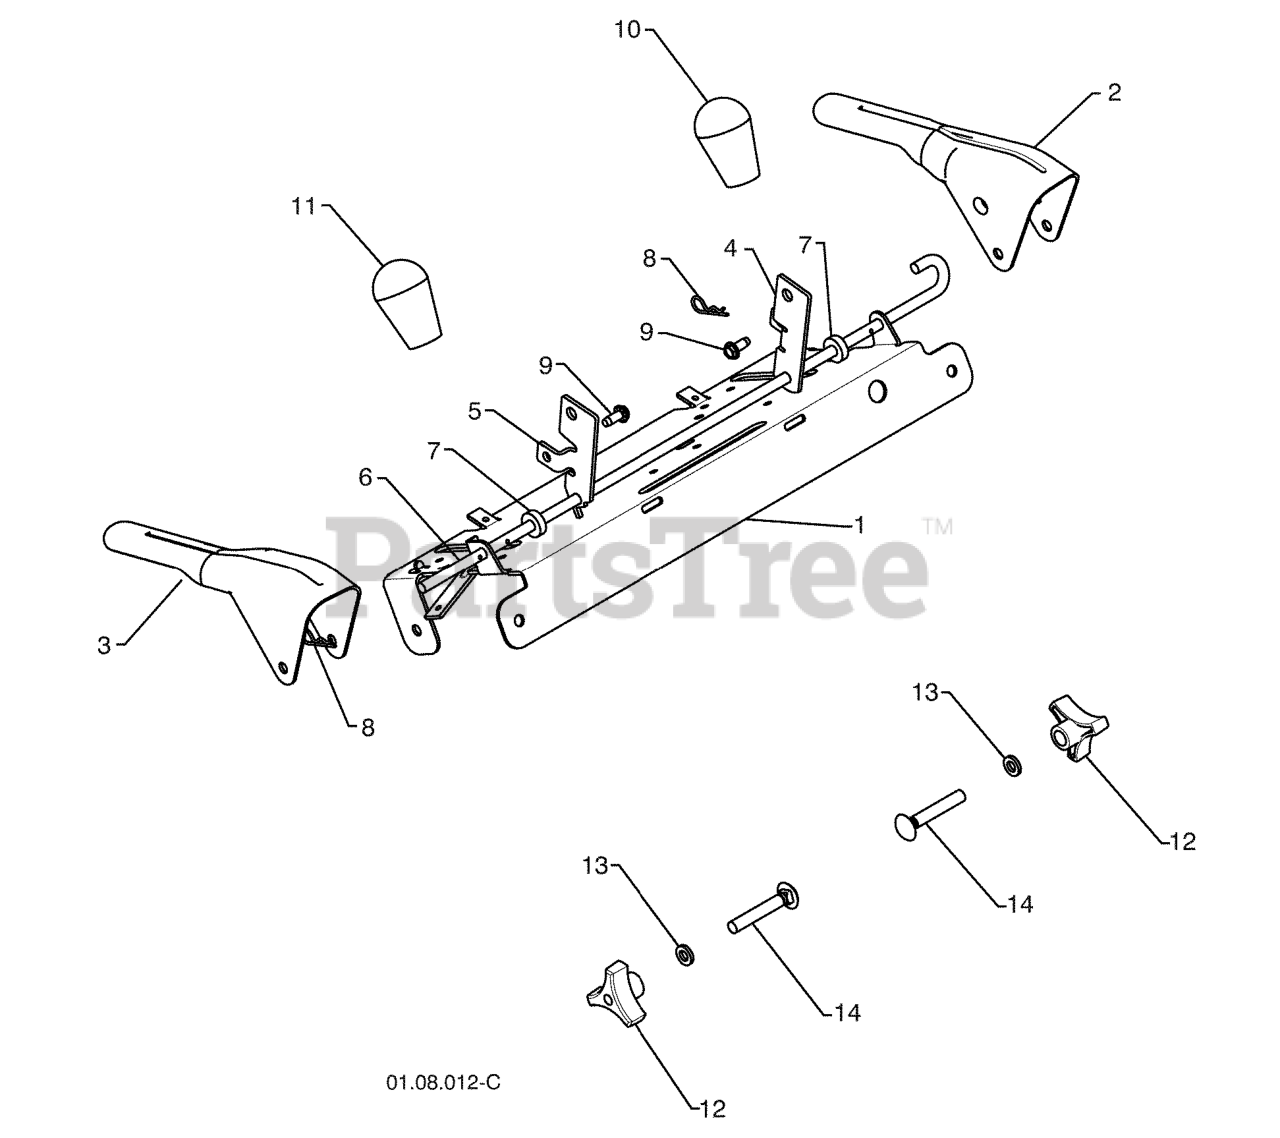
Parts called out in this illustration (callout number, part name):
1	PANEL.CONTROL.PNT.BLACK
2	LEVER.CONTROL.LH.BLACK
3	LEVER.CONTROL.RH.GREY
4	ARM.TRACTION.ROD.YZ
5	ARM.IMPELLER.ROD.SNOW
6	BAIL.CONTROL.INTERLOCK
7	SPACER.CONTROL.LEVER
8	SPRING RETAINER
9	SCREW 14-20 X 5/8
10	KNOB LEVER, BLACK
11	RED KNOB SHIFTER
12	KNOB.HANDLE.3/8.TRI-POINT.BLAC
13	WASHER
14	BOLT 3/8-16 X 2-1/4
